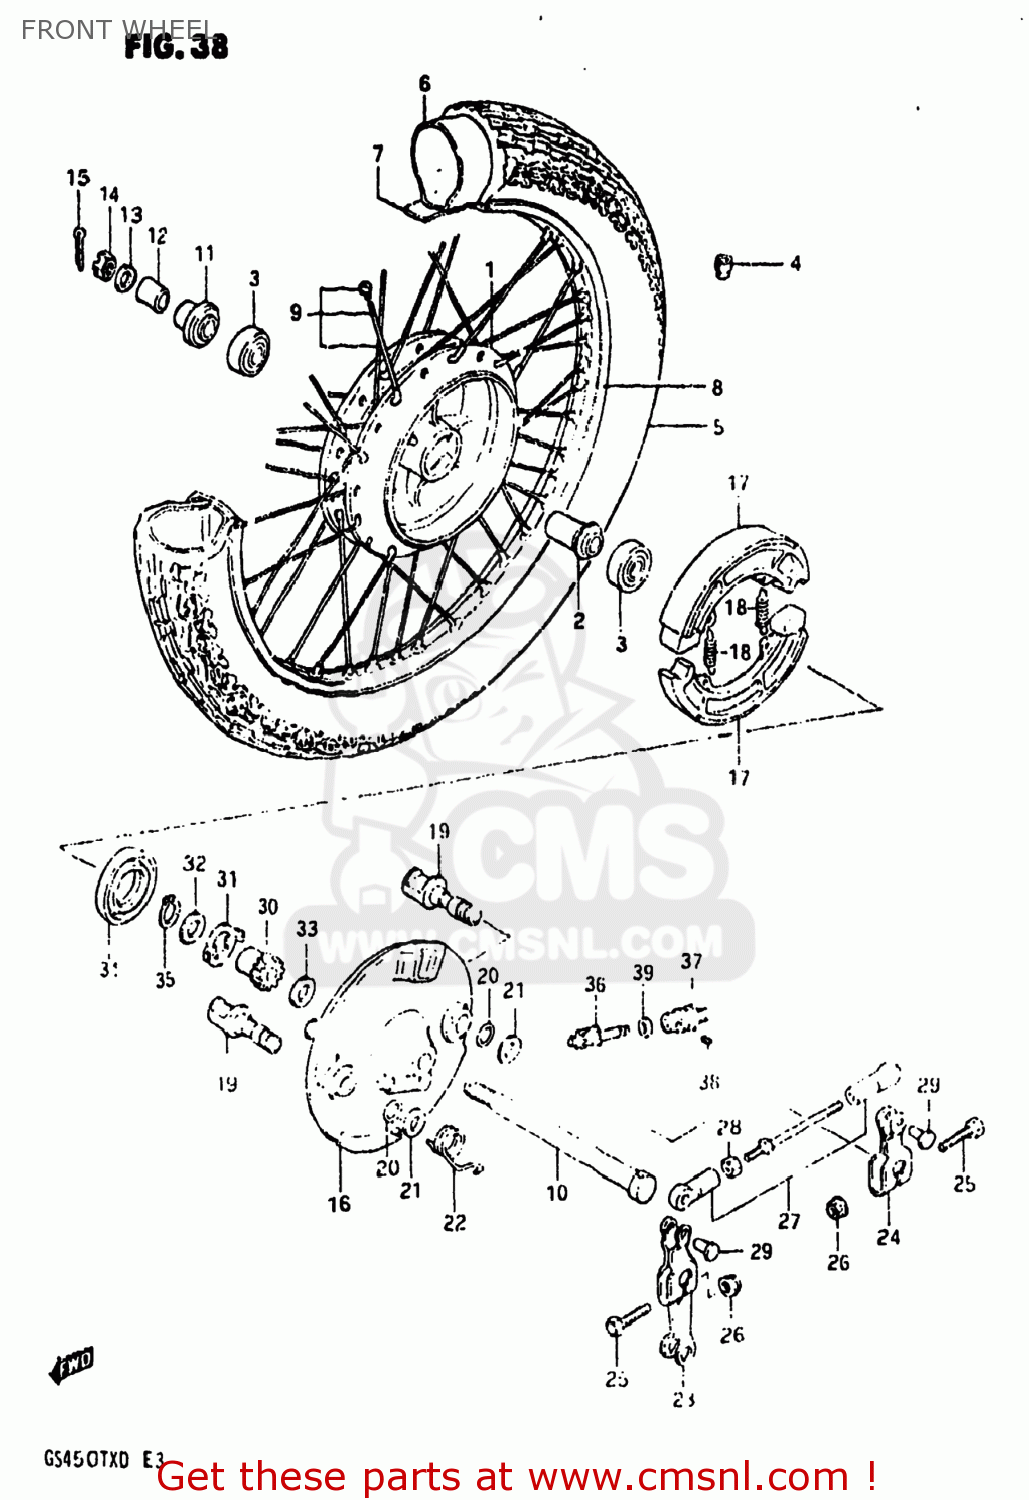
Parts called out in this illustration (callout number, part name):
1	HUB,FRONT
2	SPACER,FRONT HUB BEARING
3	BEARING
4	BALANCER,WHEEL (B)
5	TIRE
6	TUBE 2.75-19 070-483MM
7	PROTECTOR,WHL INR TUBE
8	RIM,WHEEL
9	SPOKE SET,FRONT
10	AXLE,FRONT
11	SPACER,FR AXLE,R
12	SPACER(15X22X30)
13	WASHER
14	NUT 12MM
15	COTTER PIN
16	PANEL,FRONT HUB
17	SHOE,BRAKE
18	SPRING,BRAKE SHOE
19	CAM,FRONT BRAKE
20	O-RING,BOSS
21	WASHER (15X24X1.6)
22	SPRING
23	LEVER,FRONT BRAKE CAM NO
24	LEVER,FRONT BRAKE CAM NO
25	BOLT
26	NUT
27	SHOE SET,BRAKE
28	NUT
30	GEAR,SPEEDOMETER
31	DRIVER,SPEEDOMETER GEAR
32	WASHER(22.5X27X1)
33	SHIM
34	OIL SEAL
35	CIRCLIP
36	PINION,SPEEDOMETER
37	BUSH,METER GEAR OUTER
38	SCREW
39	WASHER (5.1X9X0.4)
